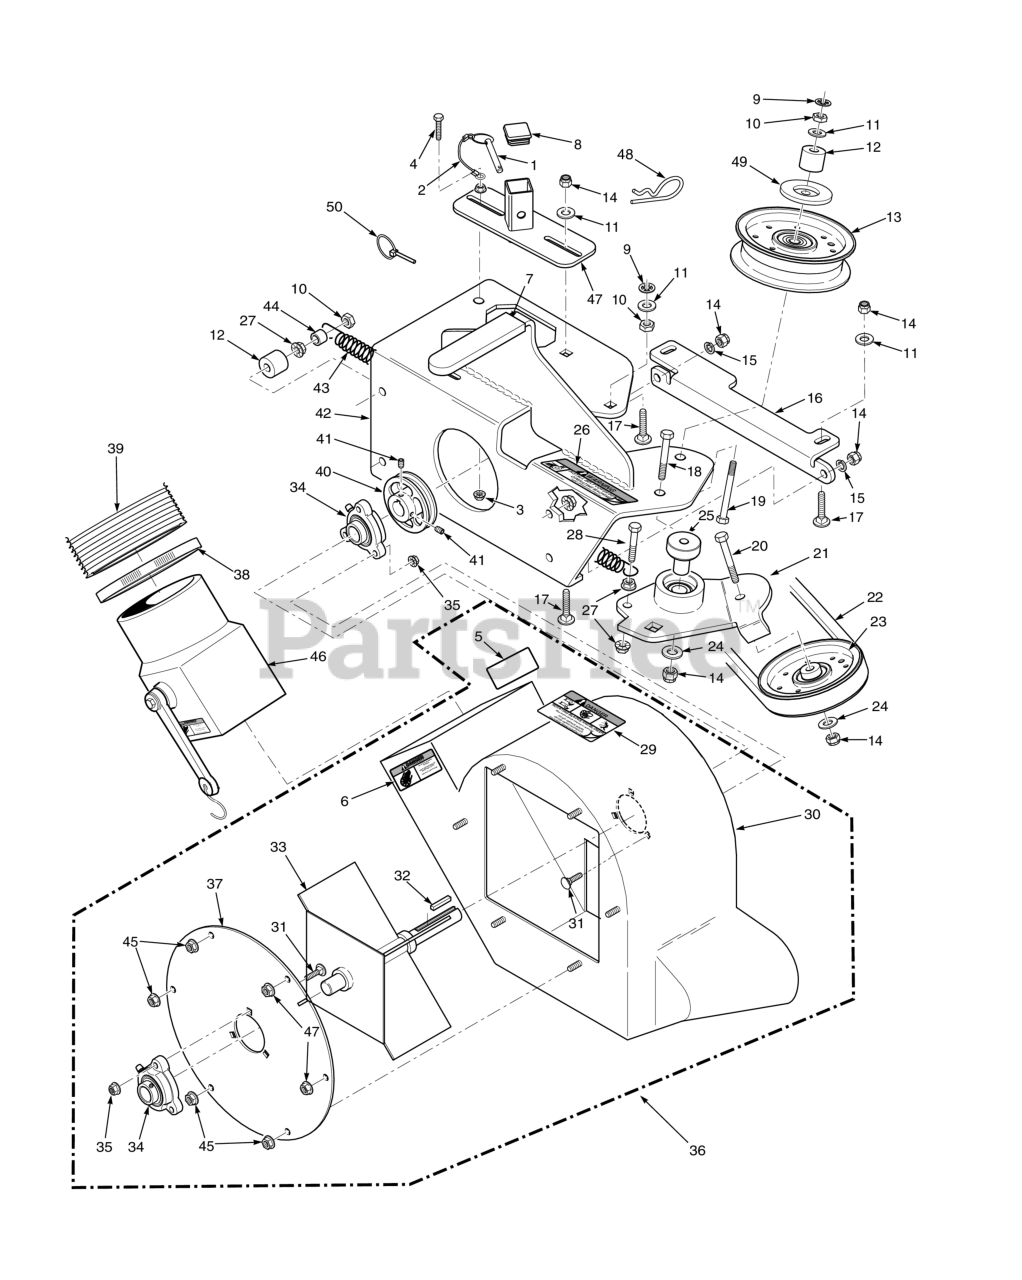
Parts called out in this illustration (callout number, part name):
1	Pin, Ring 1/2 x 2-1/4"
2	Lanyard, Deck Height Pin
3	NUT, 1/4-20 SERRATED FLANGE HEX HEAD
4	SERR. FLG. HEX HEAD CAPSCREW, 5/16-18 X 3/4
5	Decal, Blower
6	Decal, Rotating Blower
7	Grip, Deck Latch Lever
8	Cap, Square Vinyl
9	Nut, Push-On - 3/8" Dia.
10	Bolt, Hex Head 3/8-16 x 1" Ser. Flg.
11	Flatwasher, 3/8" Special (.391 x .938 x .105)
12	SPACER, J-PULL ROD
13	Pulley, Idler 4" Dia. - 61" & 72"
14	HEX NUT, ELASTIC STOP LOCK, 3/8-16
15	Lockwasher, 3/8" Spring, Kawasaki FX / FT & FT-EFI / B&S 32BV
16	Plate, Catcher Mounting
17	Bolt, RDHD Carr. 3/8-16 x 1-1/2 (52" & 61")
18	Bolt, Hex Head 3/8-16 x 3" - 52"
19	Bolt, Hex Head 3/8-16 x 3-1/2" Full Thread
20	Bolt, Hex Head 3/8-16 x 1-3/4" (Kohler EFI)
21	Idler Arm Assembly, GC-STT 61"
22	Belt, GC-STC-61V / STCII-61V
23	Pulley, 3-1/2" O.D., GC-STT 52"
24	Flatwasher, 3/8 (.391 x .938 x .105 HD) Grade 8
25	Pivot, Idler - 61" & 72"
26	Decal, Warning - Belt Cover
27	NUT, 3/8-16 SERRATED FLANGE HEX HEAD
28	Bolt, Hex Head 3/8-16 x 1-1/2" Grade 8 Black
29	Decal, Danger
30	Blower Housing Weldment w/Decals
31	Bolt, 5/16-18 x .75 RHSN Carriage
32	KEY 1/4 X 1/4 X 1 1/2"(FOR 1" CRANKSHAFT
33	Fan Weldment
34	Bearing Assembly
35	HEX NUT, ELASTIC STOP LOCK, 5/16-18
36	Blower Housing Assembly, GC-STT
37	COVER, BLOWER HOUSING
38	Clamp, 8-5/8" Max Dia. (61")
39	Hose, 8.00" Dia. x 68" Long
40	Pulley, 4-3/4" O.D. - 1" Bore
41	Setscrew, Hex Socket Knurl Cup Pt. 5/16 - 18 (nylock)
42	Frame, Blower Mount
43	Spring, Helper (61" Cutter Deck Only)
44	Spacer, Deck Assist
45	Nut, Serrated Flange 5/16-18 (Right Front Engine Mounting, Briggs and Kohler Only)
46	Adapter, Blower GC-STC,
47	Receiver Weldment, Mount Post - 61"
48	Hair Pin Cotter, .177" x 3-1/4"
49	Quick Pin, 5/16" Dia.
50	Quick Pin, 5/16" Dia.
